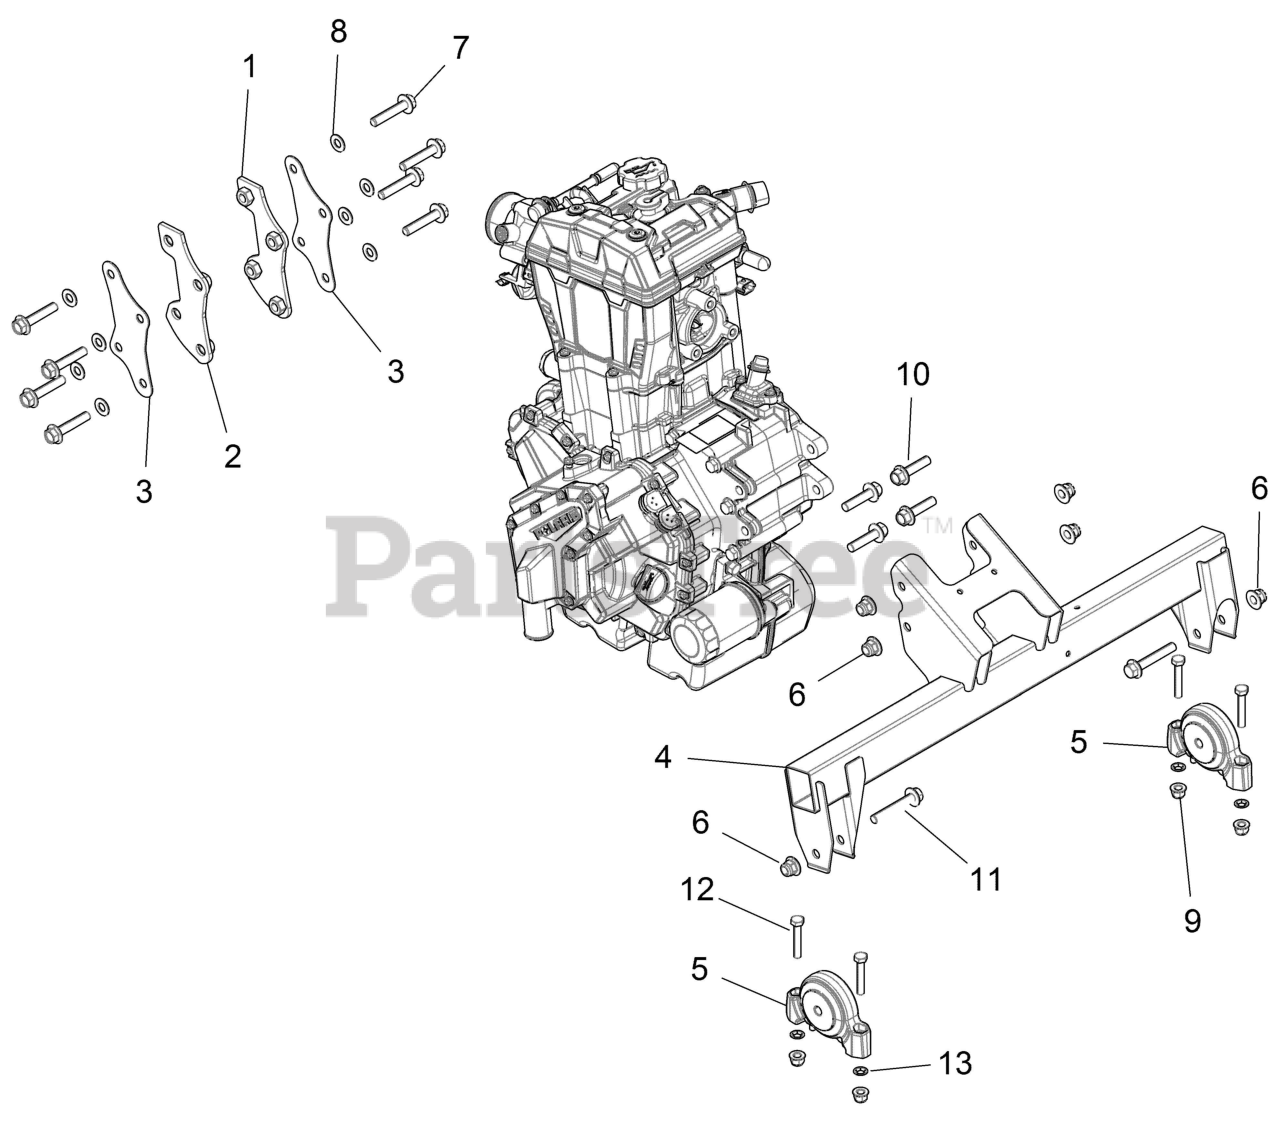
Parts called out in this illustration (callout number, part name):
1	WELD-TRANS,INNER,LEFT
2	WELD-TRANS,INNER,RIGHT
3	BRKT-COUPLER,TRANS,OUTER
4	WELD-MOUNT,ENGINE,BLK
5	MOUNT-ISOLATOR,DRIVELINE
6	NUT-M10X1.25,FLG,NYLOC-OLIVE D
7	SCR-M10X1.5X50 8.8 HX/FL ZOD
8	WASHER,3/8 FW
9	NUT-M8X1.25,FLG,NYLOC-OLIVE D
10	SCR-HXFL-M10X1.25X40 8.8 ZOD
11	BOLT-M10X1.25X60,HXFLG-OLIVE D
12	SCR-HH M8X1.25X45 8.8 ZOD
